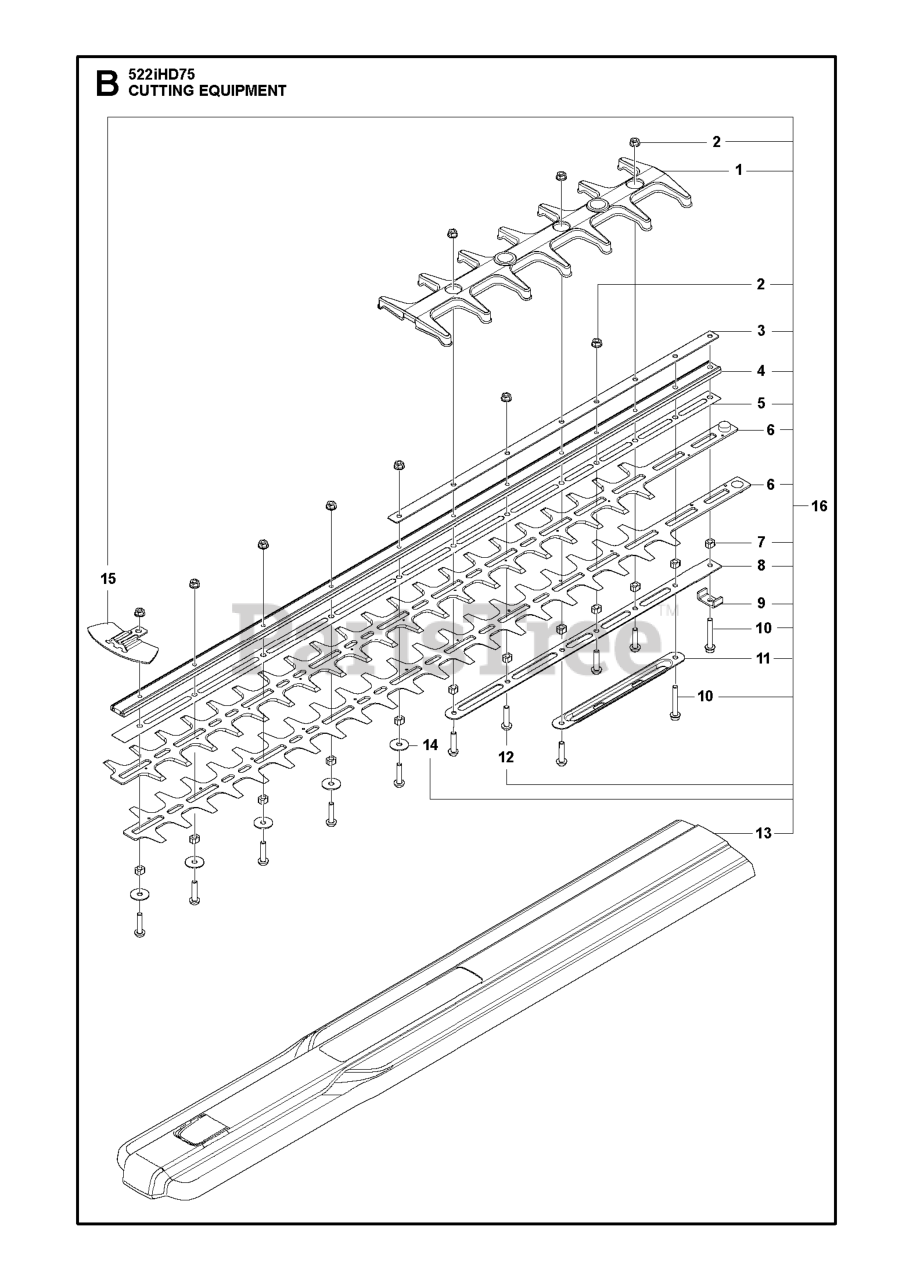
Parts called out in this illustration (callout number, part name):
1	PROTECTOR BAR ASSY HUSQVARNA
2	NUT HEXAGON LOCK WITH FLANGE M
3	BAR PLATE UPPER
5	WEAR PLATE
11	BAR PLATE LOWER
12	SCREW HEXALOBULAR SOCKET BUTTO
14	WASHER PLAIN 5.5X19X1.2 ST TBO
15	PROTECTION BLADE TIP
